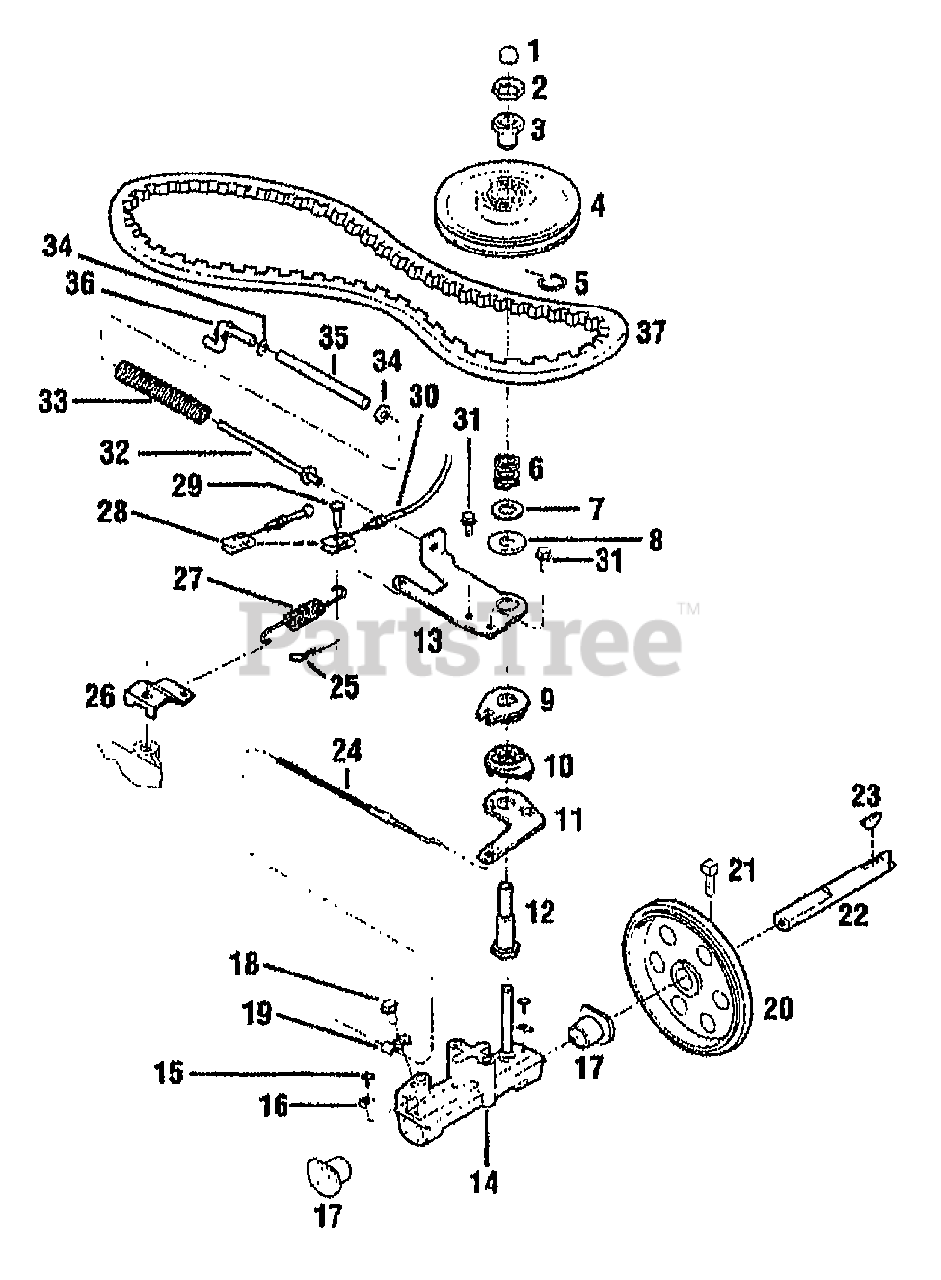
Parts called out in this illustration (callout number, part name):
2	NUT-H/LK 1/2-20
3	NUT-HEX 1/2-20X.5
4	ASSM-SHEAVE W/BEARING
5	RING, RETAINING (SNAP)
6	SPRING-COMPRESSION
7	WASHER-1.0X.632X.03 ZP
8	WASHER-.605X1.102X.08
9	PLATE-RAMP UPPER
10	PLATE-RAMP LOWER
11	ARM-CONTROL
12	SLEEVE-ADJUST
13	PLATE-ANCHOR PLATED
14	ASSM-CARRIER W/STUD
15	SCR-TORX HD
16	CLIP-BRG RETAIN BLK OXIDE
17	BEARING-CARRIER
18	SCREW, #10-24 THREAD FORMING
19	CLAMP, CABLE HOUSING
20	DISC-DRIVE/FRICTION
21	SCR-SET SQ 1/4-20 W/NYLOC
22	AXLE-DRIVE ROUND NGMM
23	KEY-WOODRUFF .125X.5
24	CABLE-DRIVE CONTROL
25	PIN-CLIP .08
27	SPRING-SPEED CONTROL
28	CABLE-SINGLE SPD CONTROL {34321,34321C}
29	PIN-SPEED CONTROL
30	ASSM-ARM CONTROL {NOT 34320,34320C,34044}
31	SCR-FLANGE 1/4-20X3/4 GR5
32	ROD-BELT ADJ
33	SPRING-COMPRESSION
34	WASHER-FLAT 1/4 SAE
35	SLEEVE-BELT
36	KIT-SVC ANCHOR, ROD
37	BELT-V NGMM
